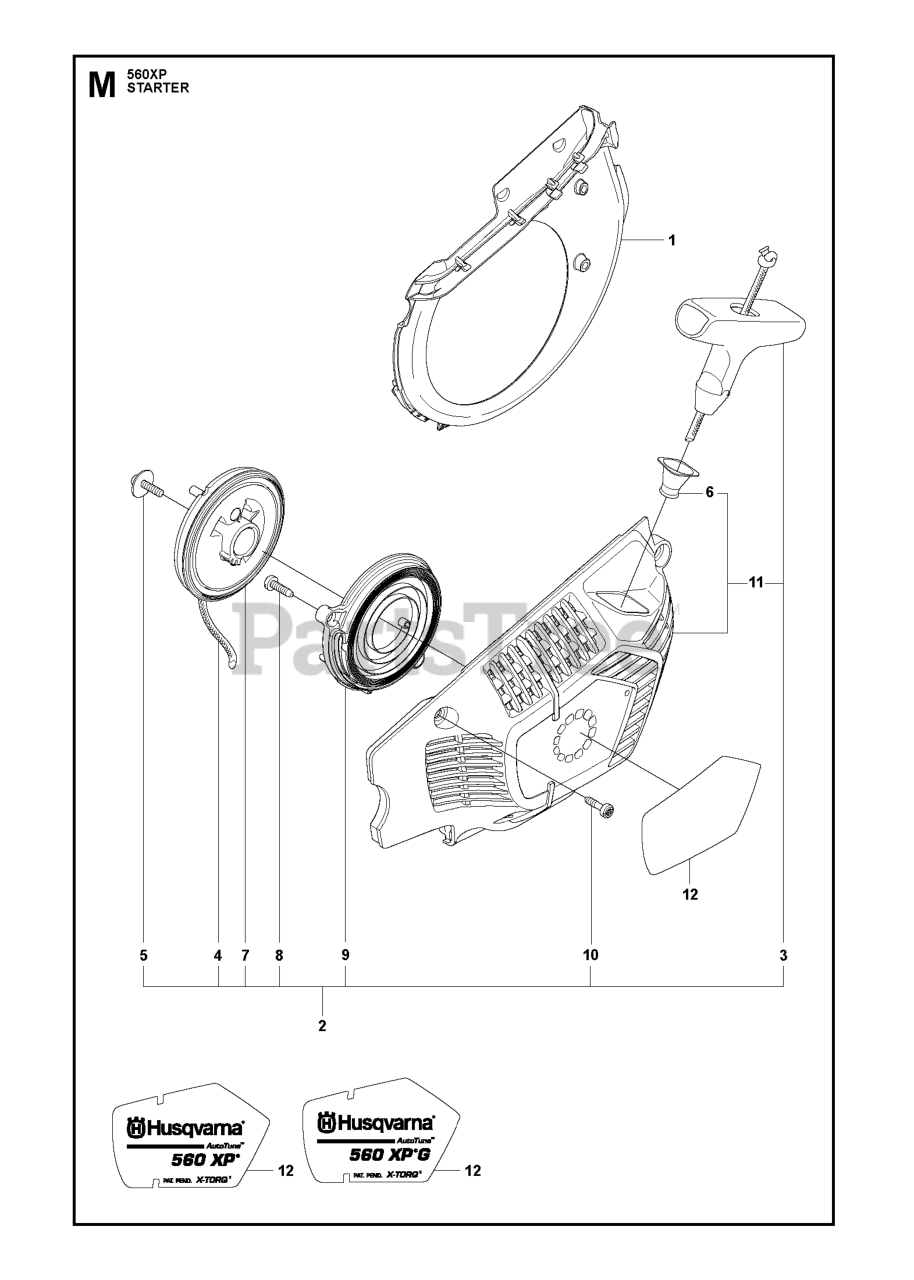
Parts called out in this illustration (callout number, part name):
1	COOLING AIR CONDUCTOR
4	STARTER ROPE
5	SCREW ITXSCT MT5X16 10.9 TBO
7	STARTER PULLEY ASSY
8	SCREW CITXPANT
10	SCREW CITXPANMO
11	STARTER HOUSING
12	LABEL XP
12	LABEL XPG
